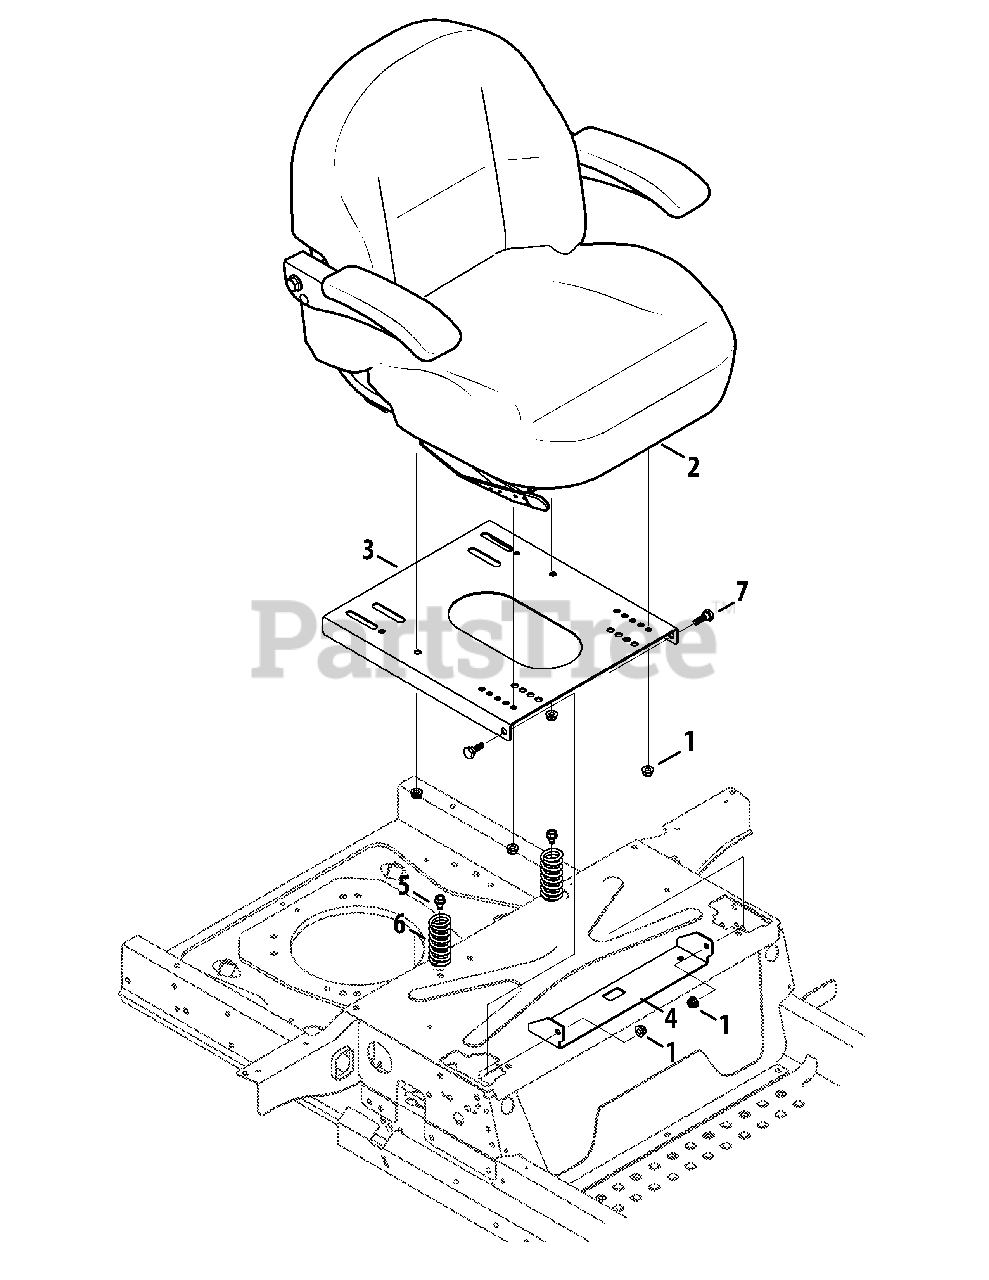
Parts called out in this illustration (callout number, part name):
1	Flange Lock Nut, 5/16-18
3	Seat Plate
4	SEAT PIVOT BRACKET (POWDER BLACK)
5	Hex Washer Screw, 5/16-18 x .750
6	Compression Spring, 1.28 x 3.125
7	Shoulder Screw, 5/16-18 x .437 x .268
